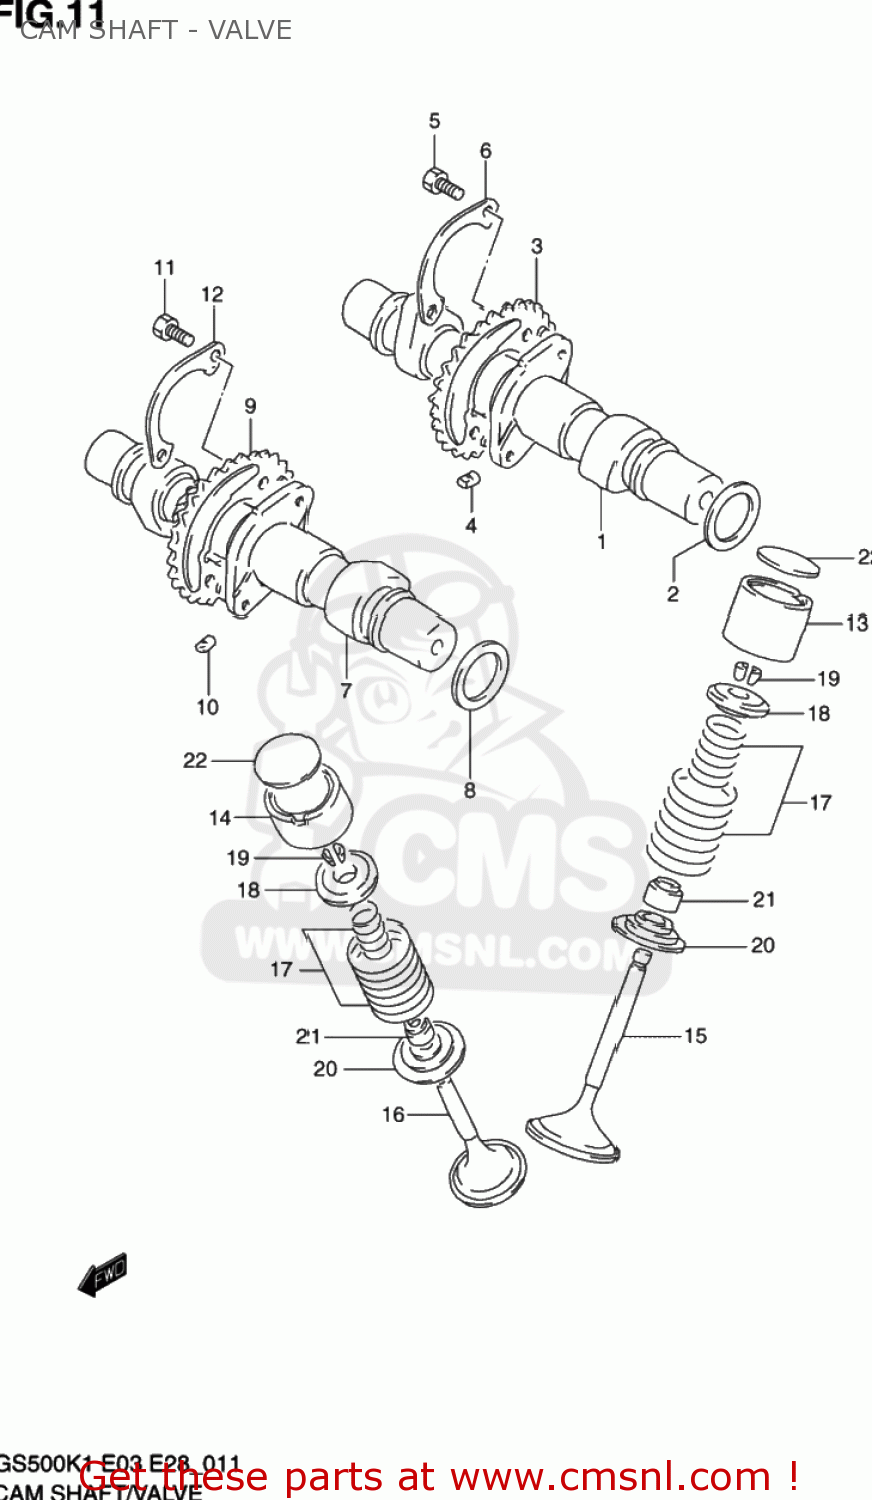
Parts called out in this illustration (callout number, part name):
1	CAMSHAFT SET,I
2	SHIM(22X30X1)
3	SPROCKET,CAMSHAFT INTAKE
4	PIN,SPROCKET
5	BOLT(6X12.5)
6	WASHER,CAM CHAIN SPROCKET
7	CAMSHAFT SET,EXHAUST
8	SHIM(22X30X1)
9	SPROCKET,EXHAUST CAM(NT:30)
10	PIN,SPROCKET
11	BOLT(6X12.5)
12	WASHER,CAM CHAIN SPROCKET
13	TAPPET
14	TAPPET
15	VALVE,INTAKE
16	VALVE,EXHAUST
17	SPRING SET,VALVE
18	RETAINER,VALVE SPRING
19	COTTER VALVE
20	SEAT,VALVE SPRING
21	SEAL,OIL(7X14.4X9)
22	SHIM,TAPPET(T:2.15)
23	SHIM SET,TAPPET
24	CASE,SHIM
